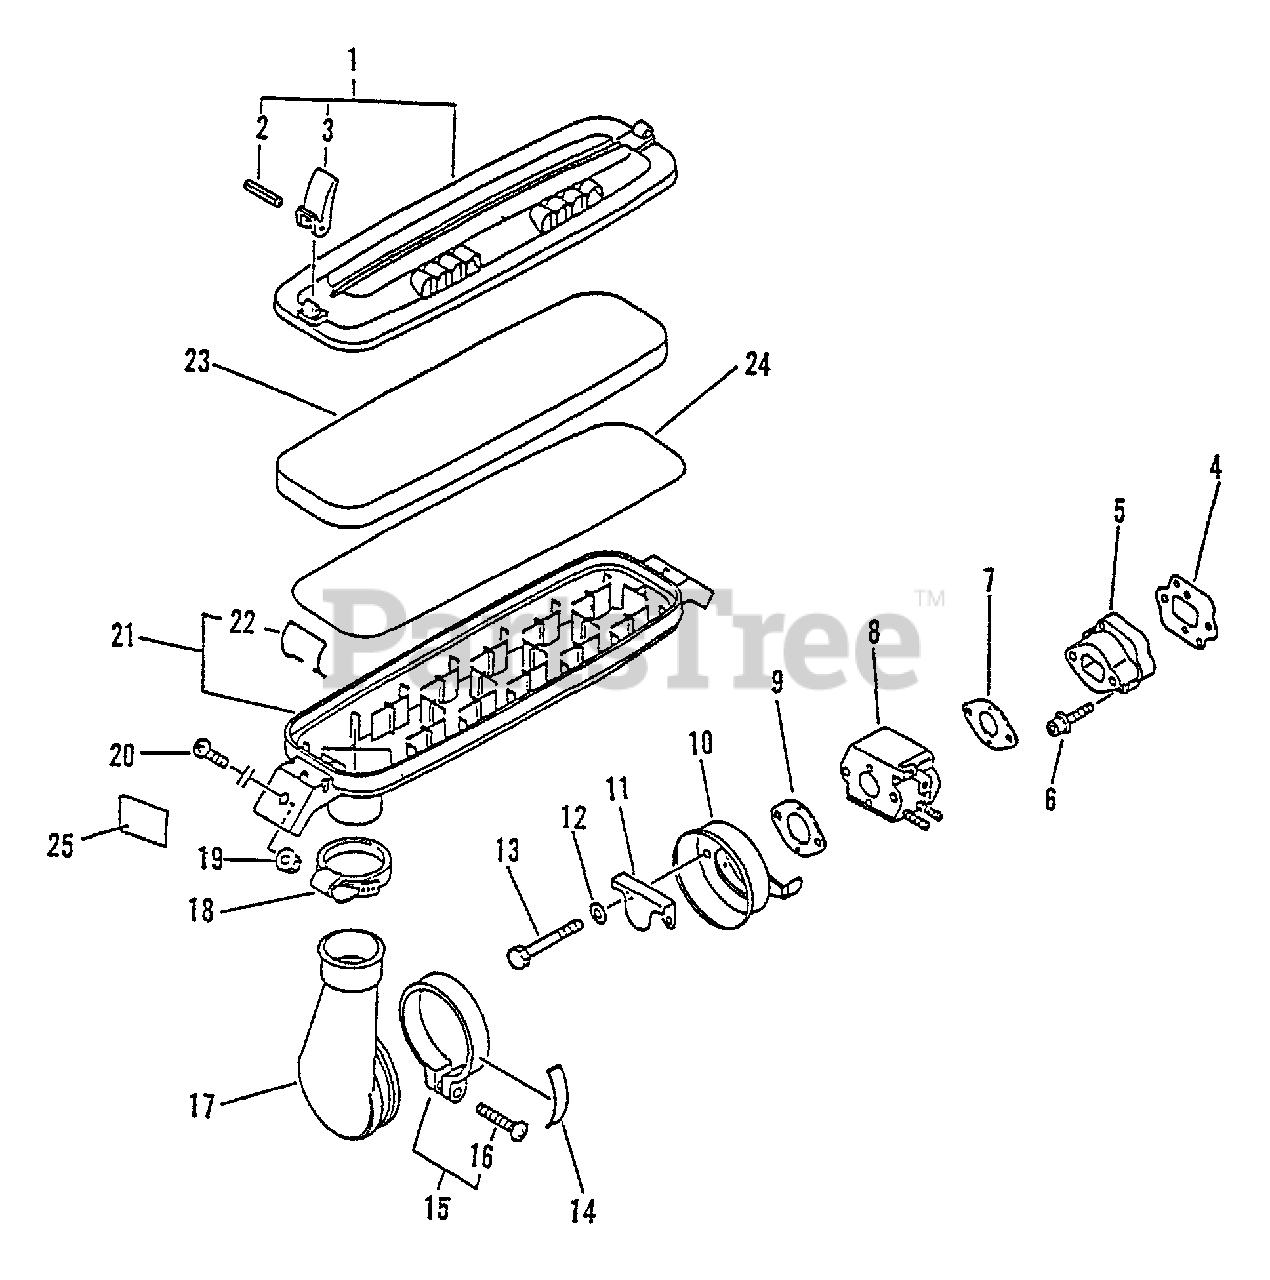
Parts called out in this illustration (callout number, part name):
1	COVER, AIR FILTER
2	PIN - SPRING -- 3X25
3	KNOB
4	GASKET, INTAKE
5	INSULATOR, INTAKE
6	SCREW - 5X25
7	GASKET, INTAKE
8	CARBURETOR C1M-K24A
9	GASKET, INTAKE
10	BRACKET, AIR CLEANER
11	PLATE, PREVENT
12	WASHER - 5
13	SCREW - 5X55
14	LABEL - CHOKE
15	CLAMP KIT
16	SCREW - 5X25
17	ADAPTOR, INTAKE
18	CLAMP
19	NUT - 5 -- FLANGE
20	SCREW - 5X14
21	AIR FILTER CASE ASSY
22	RING, RETAINING
23	FILTER, AIR
24	FILTER, AIR - FOAM
25	TIE, CABLE - LARGE
